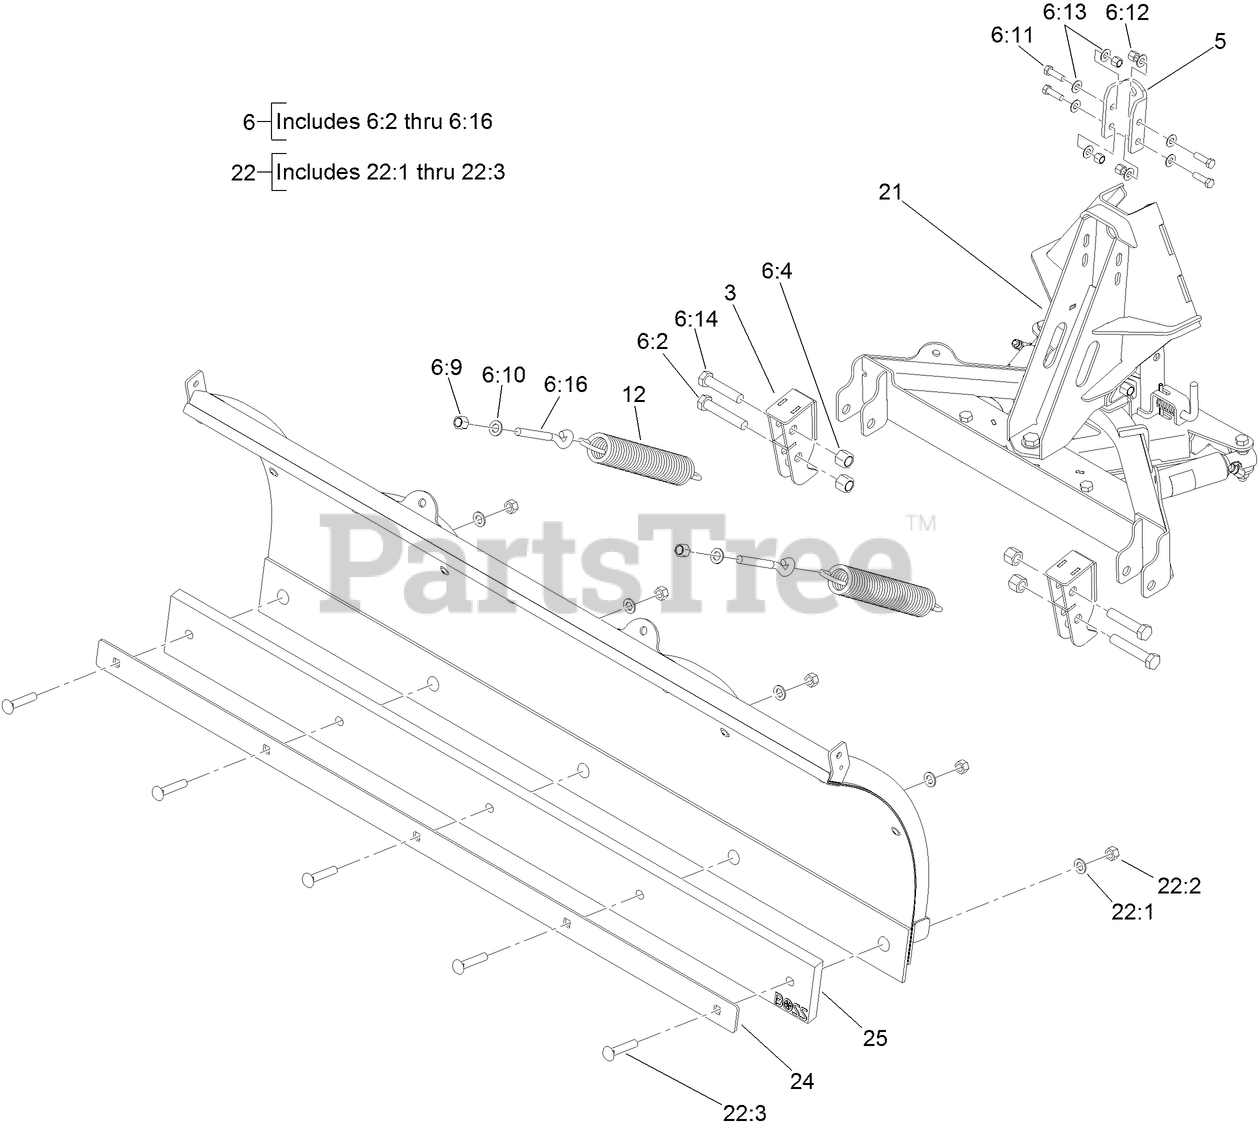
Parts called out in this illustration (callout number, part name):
3	MOUNT ASM,LIM-ADJUST,STB,GRANDSTAND
5	COUPLER,PIN C-CHANNEL,GRANDSTAND
6	KIT-HDW,GRANDSTAND,PLOW SIDE
6:2	HHCS,5/8-11X3-1/2,GR5,YZN
6:4	NUT,5/8-11,NYL INS,YZN
6:9	NUT,1/2-13,NYL INS,YZN
6:10	WASHER,1/2,F436 HARD,F/W,YZN
6:11	HHCS,3/8-16X1-1/4,NC,GR5,YZN
6:12	NUT,3/8-16,NYL INS,YZN
6:13	WASHER,FLAT,3/8ST/ST 18-8
6:14	HHCS,5/8-11X3,GR5,YZN
6:16	EYE BOLT,1/2-13X5-1/4(TO CEN),YZN
12	SPRING,TRIP,STB,ATV/UTV
21	PUSHFRAME,COUPLER ASM,GRANDSTAND
22	FASTENER KIT,URETHANE EDGE 3/4' THK,ST
22:1	WASHER,1/2,F436 HARD,F/W,YZN
22:2	NUT,1/2-13,TOP L/N,GRB,CADWAX,YZN
22:3	BOLT,CARRIAGE,1/2'-13X2-1/2',GR5 BLKZ
24	STRAP,CUT EDGE,POLY,5,ATV/UTV,STB
25	CUTTING EDGE,URETHANE,5'X4'X3/4',STB
